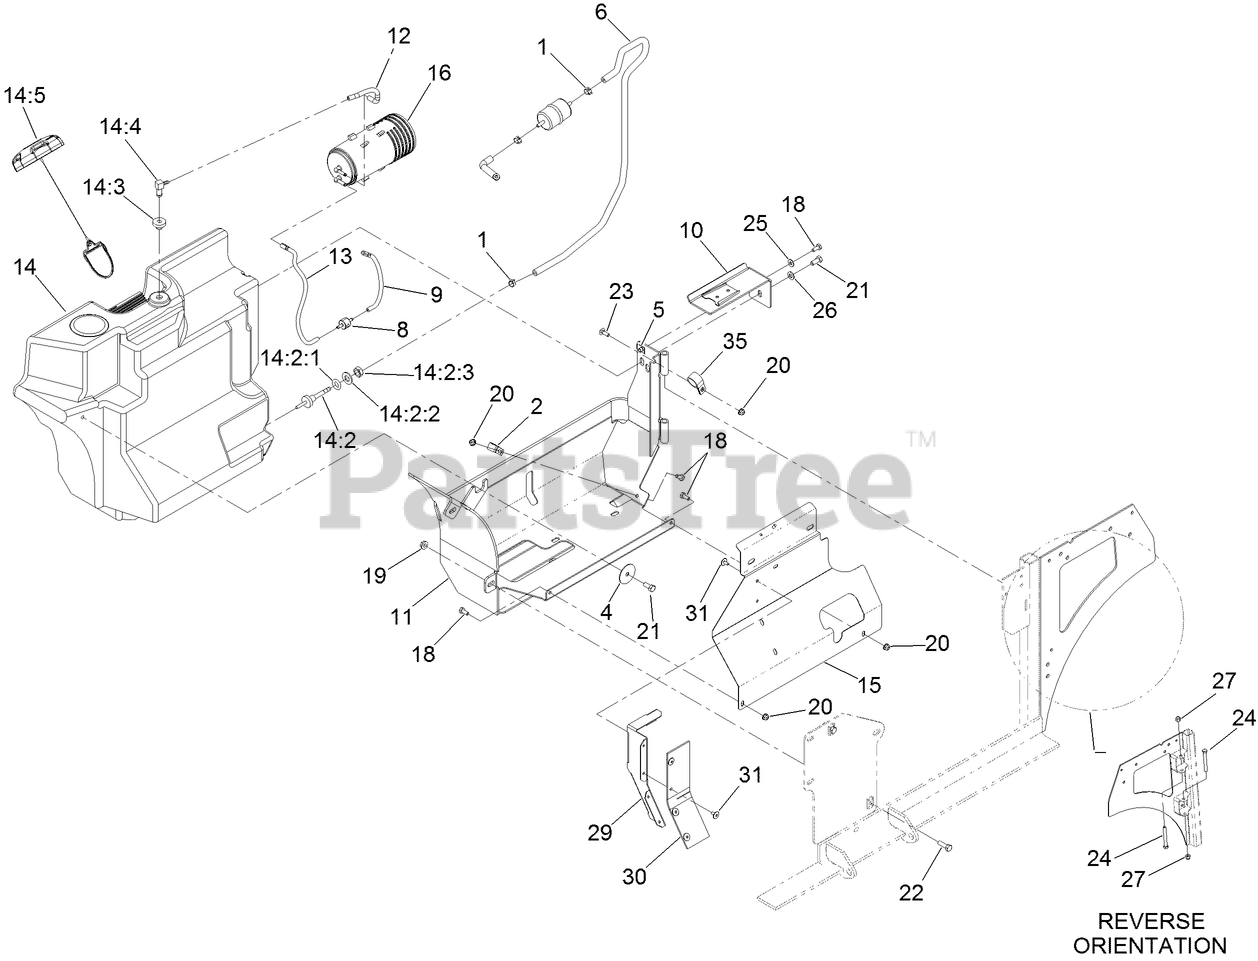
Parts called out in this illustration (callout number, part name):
1	CLAMP-HOSE
2	CLIP-LOOM
4	WASHER
6	HOSE-FUEL
8	VALVE-CHECK, VACUUM
9	HOSE-VENT, FORMED
10	CANISTER BRACKET ASM
11	TANK FRAME ASM
12	HOSE-VENT, FORMED
13	HOSE-VENT, FORMED
14	FUEL TANK ASM
14:2	FITTING-FUEL, BULKHEAD
14:2:1	O-RING,BULKHEAD FITTING
14:2:2	WASHER-FLAT
14:2:3	NUT-JAM
14:3	BUSHING
14:5	CAP-FUEL, RATCHETING
15	PANEL-TANK SHIELD
16	CANISTER-CARBON, 800CC
18	SCREW-HH
19	NUT-HF
20	NUT-HF
21	SCREW-HH
22	SCREW-HH
23	BOLT-CARR
24	SCREW-HH
25	WASHER-FLAT
26	WASHER-PLAIN
27	NUT-LOCK, NI
29	DEFLECTOR-AIR
30	FLAP-RUBBER
31	RIVET-POP
35	R-CLAMP
